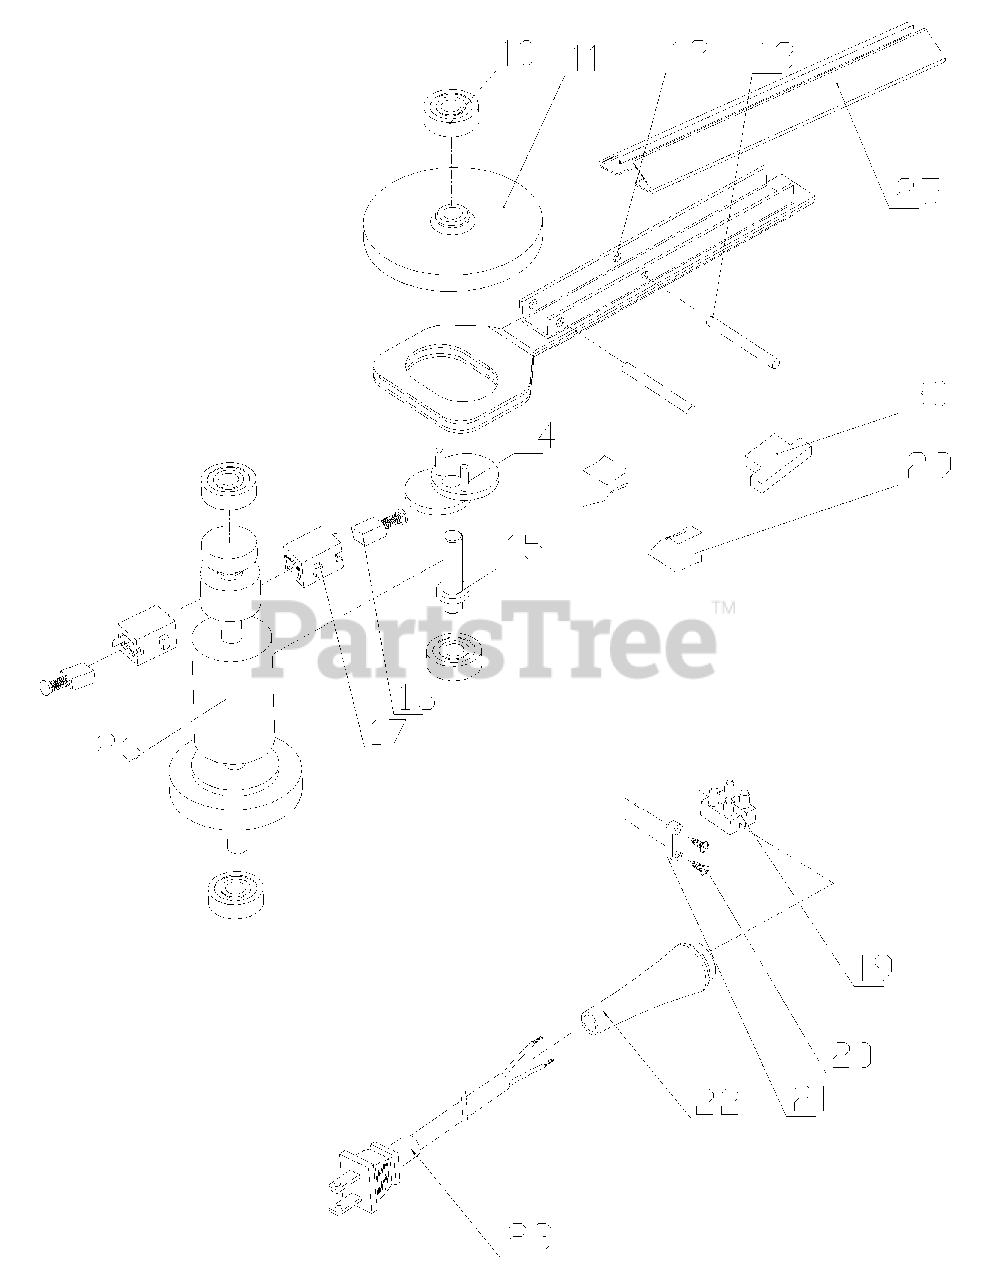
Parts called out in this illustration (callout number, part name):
7	HOUSING (L)
9	FIELD ASS'Y
12	22" BLADE
14	ECCENTRIC SHAFT
15	OUTPUT SHAFT
17	BRUSH HOLDER
18	HOUSING (R)
19	TERMINAL BLOCK
21	STRAIN RELIEF
22	CORD GUARD
23	POWER CORD
25	BLADE COVER
31	LABEL (R)
32	LABEL (L)
